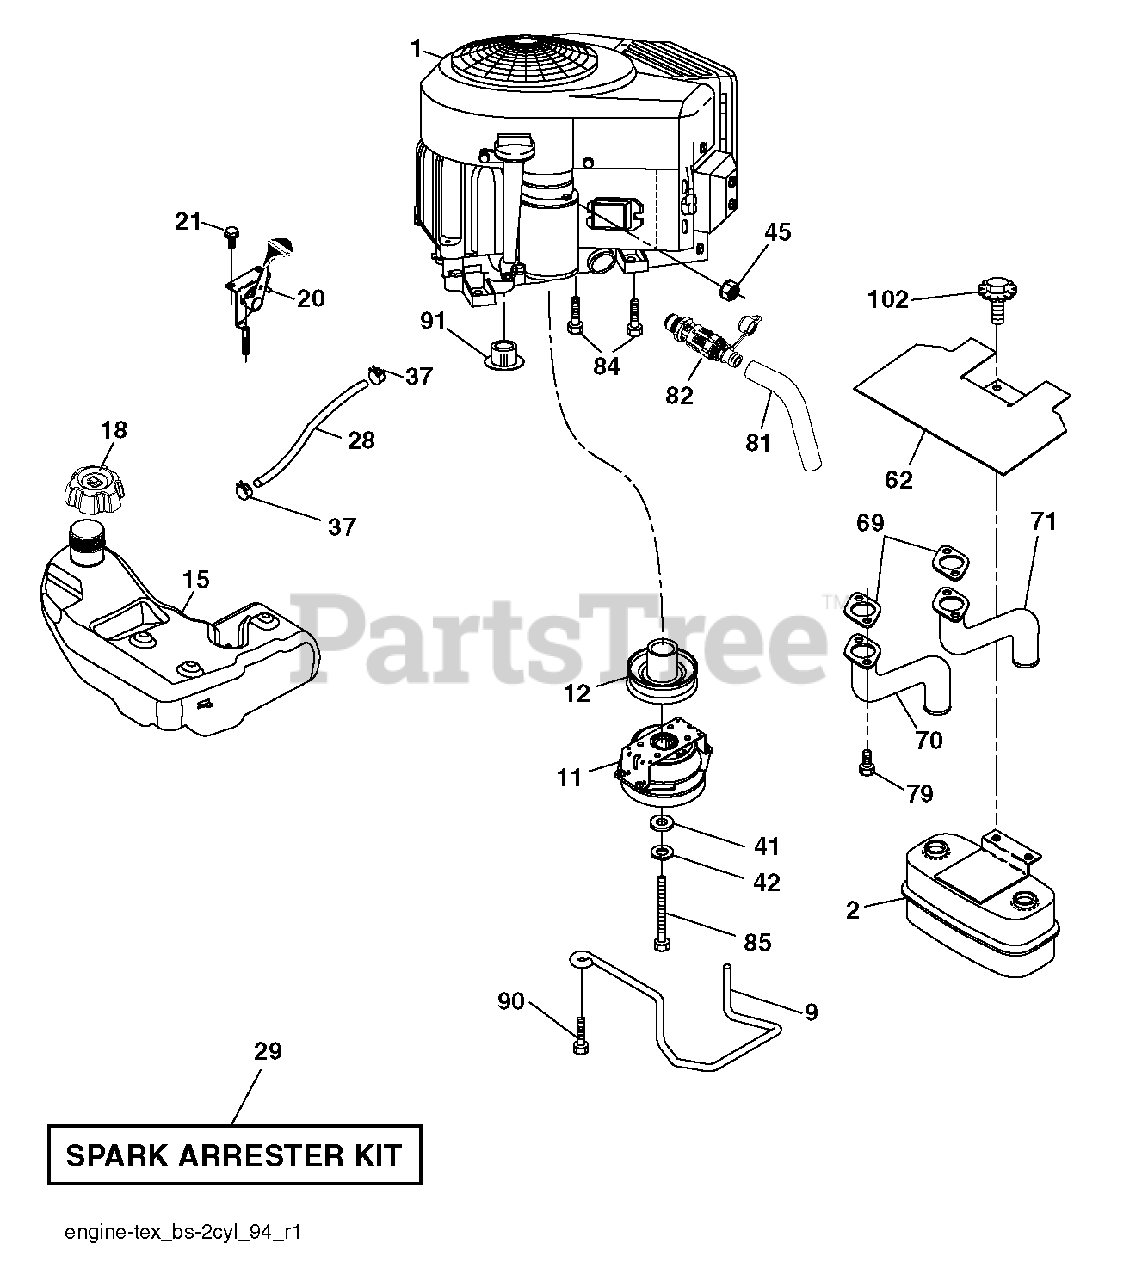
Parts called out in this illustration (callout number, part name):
2	MUFFLER.ASM.TWN.EXTNDED.DFLCTR
9	KEEPER BELT ENGINE
11	CLUTCH ELECTRIC
12	PULLEY ENGINE
15	TANK.FUEL.4GAL
18	Fuel Tank Cap Assembly, 3" N-EPA Black
20	CONTROL.TH/CK.COBRA.B&S.TWN.
21	SCREW.#10 X 0.750.BOS (2 2)
28	HOSE.1/4".FUEL.LINE.64".LENGTH
29	KIT.SPARK ARRESTOR(392390 B&S)
37	HOSE CLAMP
42	LOCKWASHER
45	NUT
62	SHIELD.HEAT.MUFFLER
69	GASKET.MUFFLER
70	EXHAUST.TUBE.LH.BS/TWIN
71	EXHAUST.TUBE.RH.B&S.TWIN.INTEK
79	SCREW.SOCKET.HEAD.5/16-18
81	TUBE, DRAIN OIL ASM.
82	VALUE.OIL.DRAIN
84	SCREW.3/8-16
85	BOLT HEX 7/16-20 X 3.75 GR. 5
90	SCREW 3/8-16X1
91	BUSHING.1.375OD
102	SCREW
